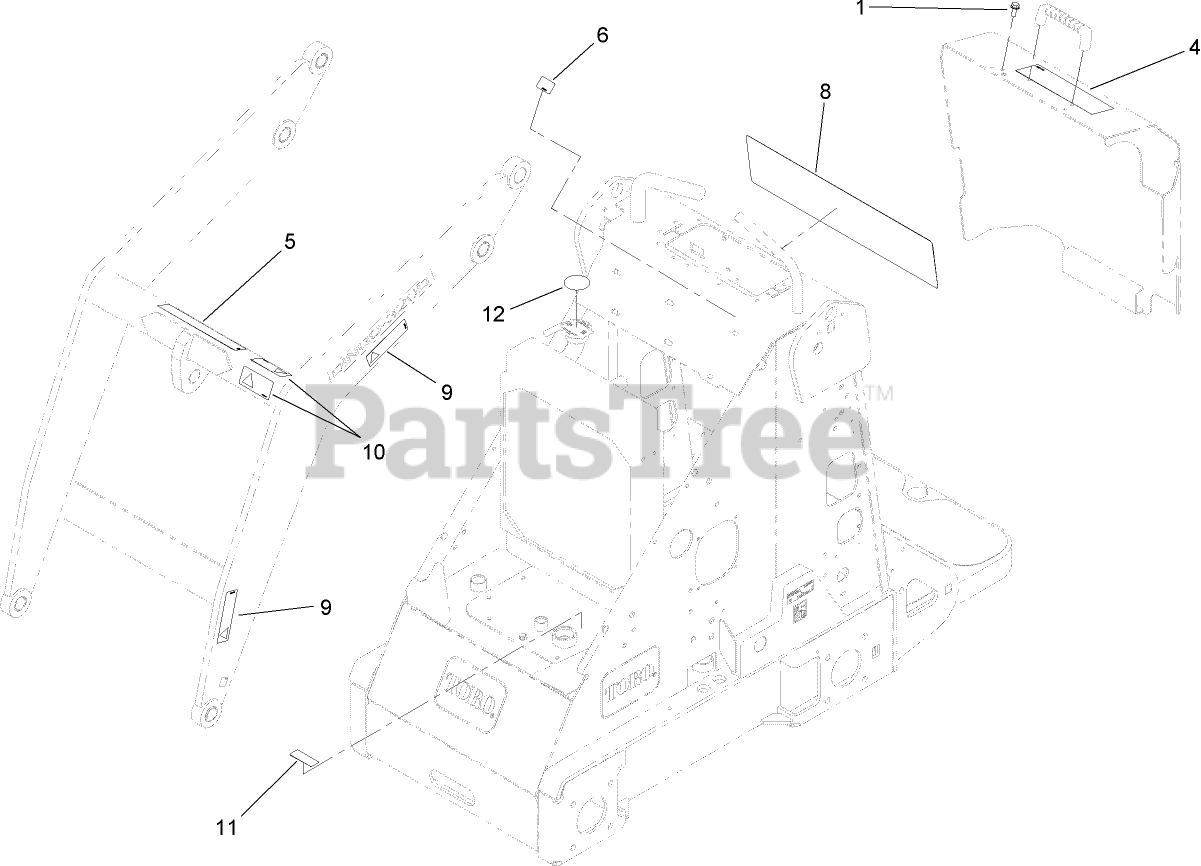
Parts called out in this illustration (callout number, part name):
1	SCREW-HWHTF
4	DECAL-DANGER
5	DECAL-CAUTION
6	DECAL-LIMITER, SPEED
8	DECAL-CONTROL PANEL, CE
9	DECAL-WARNING, PINCH
10	DECAL-NO RIDER
11	DECAL-OIL, HYD
12	DECAL-WARNING
